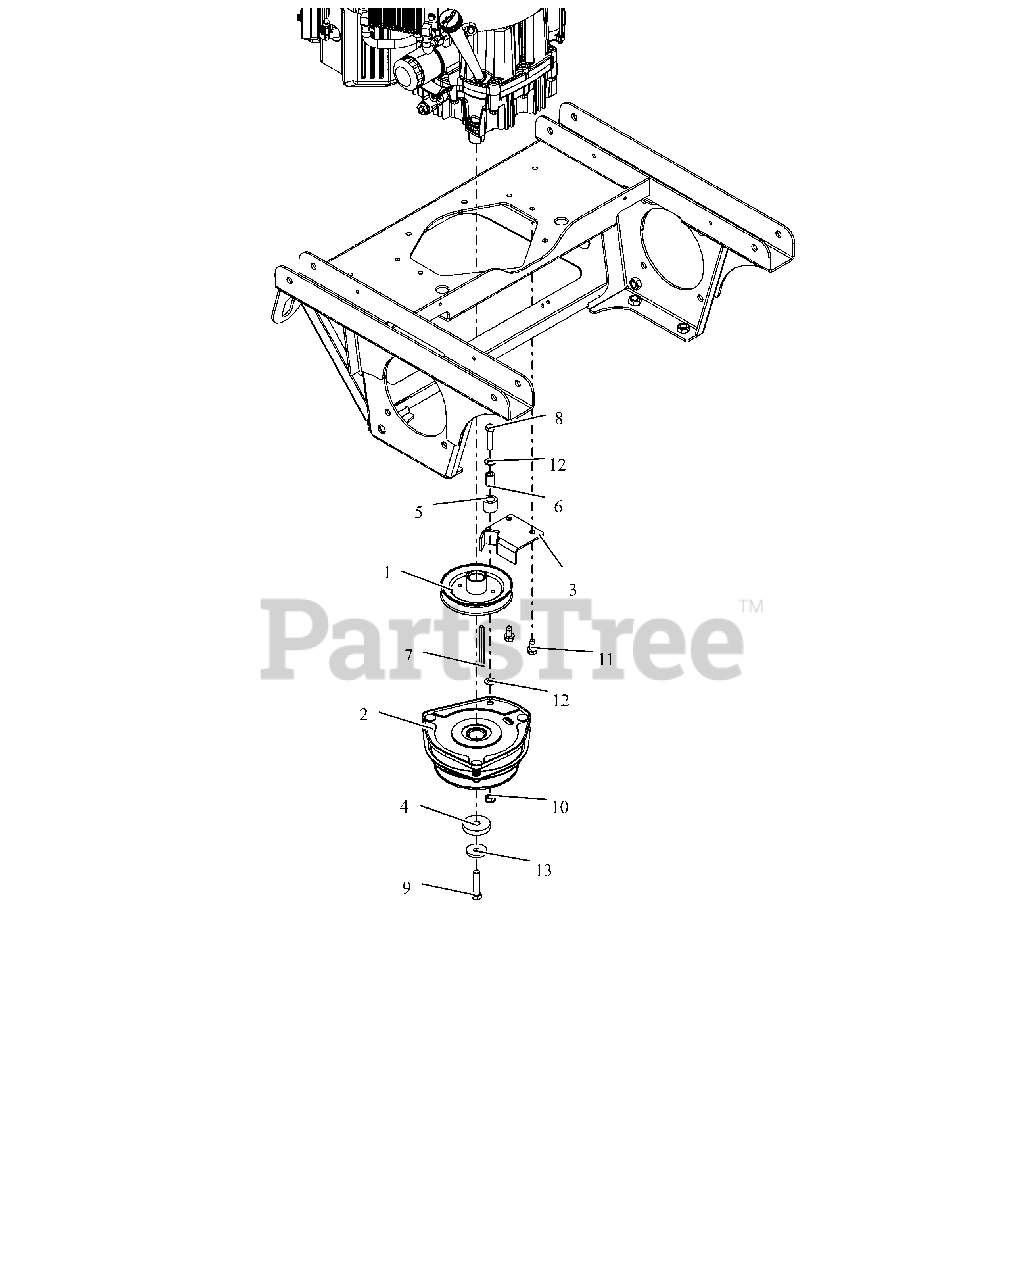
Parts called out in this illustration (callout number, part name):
1	SHEAVE-ENGINE 1.127ID X 5.25OD
2	CLUTCH, ELE-OGURA GT3.5-VP01R
3	CLUTCH STOP WLDMT - BLACK
4	SPACER, .450X2.00X.396
5	BUMPER,RUBBER .62X1.0X.88 LG
6	BUSH.,S.391X.622X.950 ST
7	KEY-SQ. .25X3.50X.25 SAE
8	BLT, HEX .38-16X1.75 G5 ZCC
9	BLT, HEX 0.4375-20X2 G8 ZCC NT
10	NUT-LK-TOP-FLG .38-16 ZC120
11	SCR,TAP .375-16X.75 HWH TR ZCC
12	WSHR,FLT .406X.812X.065 ZCC
13	WASHER, 7/16" SPRING DISK
